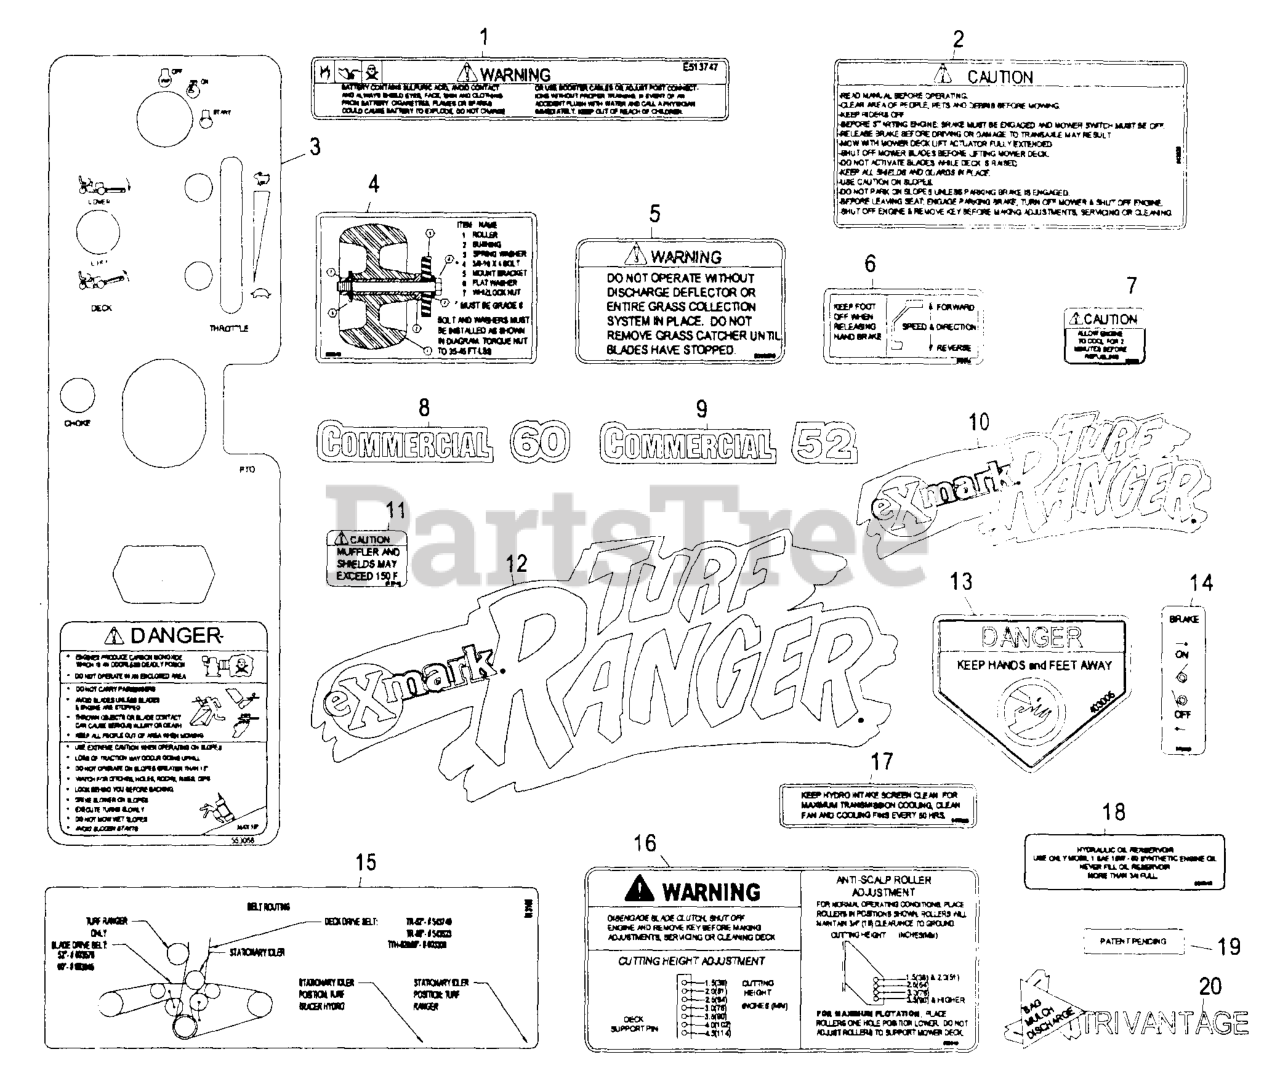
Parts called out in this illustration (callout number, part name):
1	DECAL-BATTERY
4	DECAL,ROLLER MOUNTING
5	DECAL-WARNING, DISCHARGE
6	DECAL,FOOT PEDAL
8	DECAL,COMMERCIAL 60
9	DECAL,COMMERCIAL 52
12	DECAL,SWASH RANGER
13	DECAL-DANGER
15	DECAL,BELT ROUTING
16	DECAL,ANTI SCALP
17	DECAL,INTAKE
18	DECAL,HYDRAULIC TANK
19	Decal, Patent Pending
